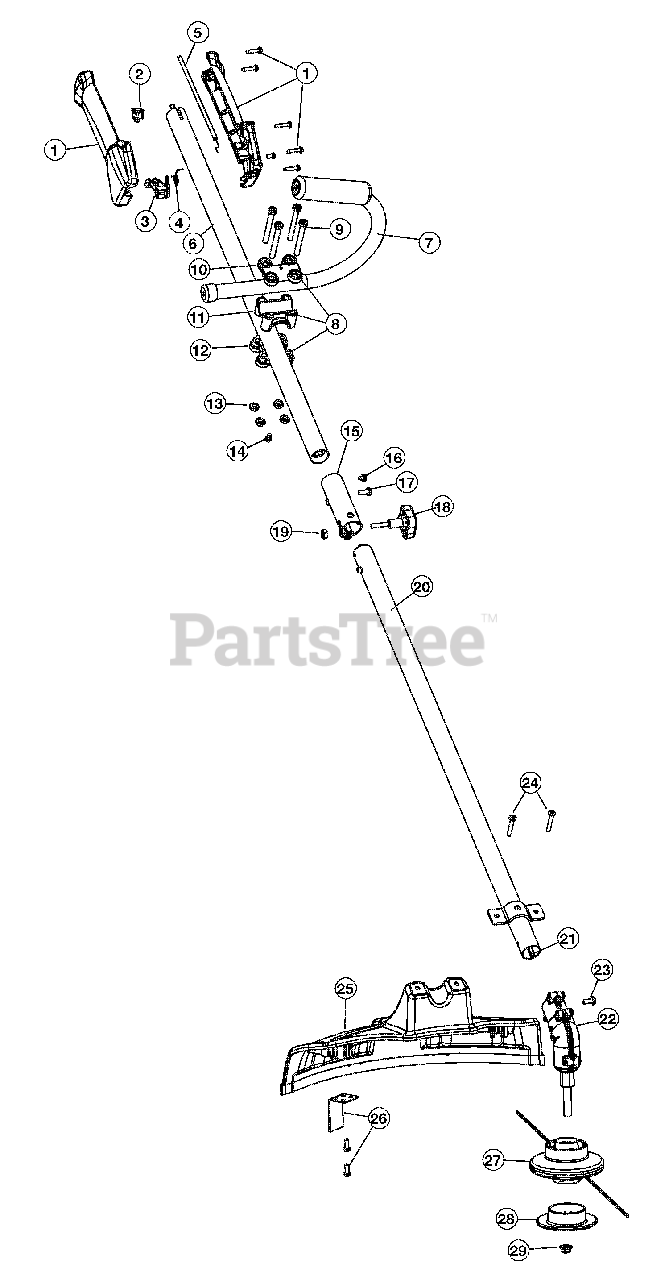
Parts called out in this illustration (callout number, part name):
1	Throttle Housing Assembly
3	Throttle Trigger
4	Throttle Trigger Spring
5	Throttle Cable
6	Upper Drive Shaft Housing
7	J-Hable Assembly
8	Handle Bracket Assembly
10	Upper Handle Clamp
11	Middle Handle Clamp
12	Lower Handle Clamp
14	Anti-Rotation Screw
15	Split Book Coupler
18	Adjustment Knob
19	Knob Retaining Nut
20	Lower Drive Shaft Housing Assembly
21	Lower Flexiable Drive Shaft
22	Gearbox Assembly
23	Anti-Rotation Screw
24	Shield Mounting Hardware
25	Shield Assembly
26	Blade Assembly
27	Flixed Line Head Assembly
